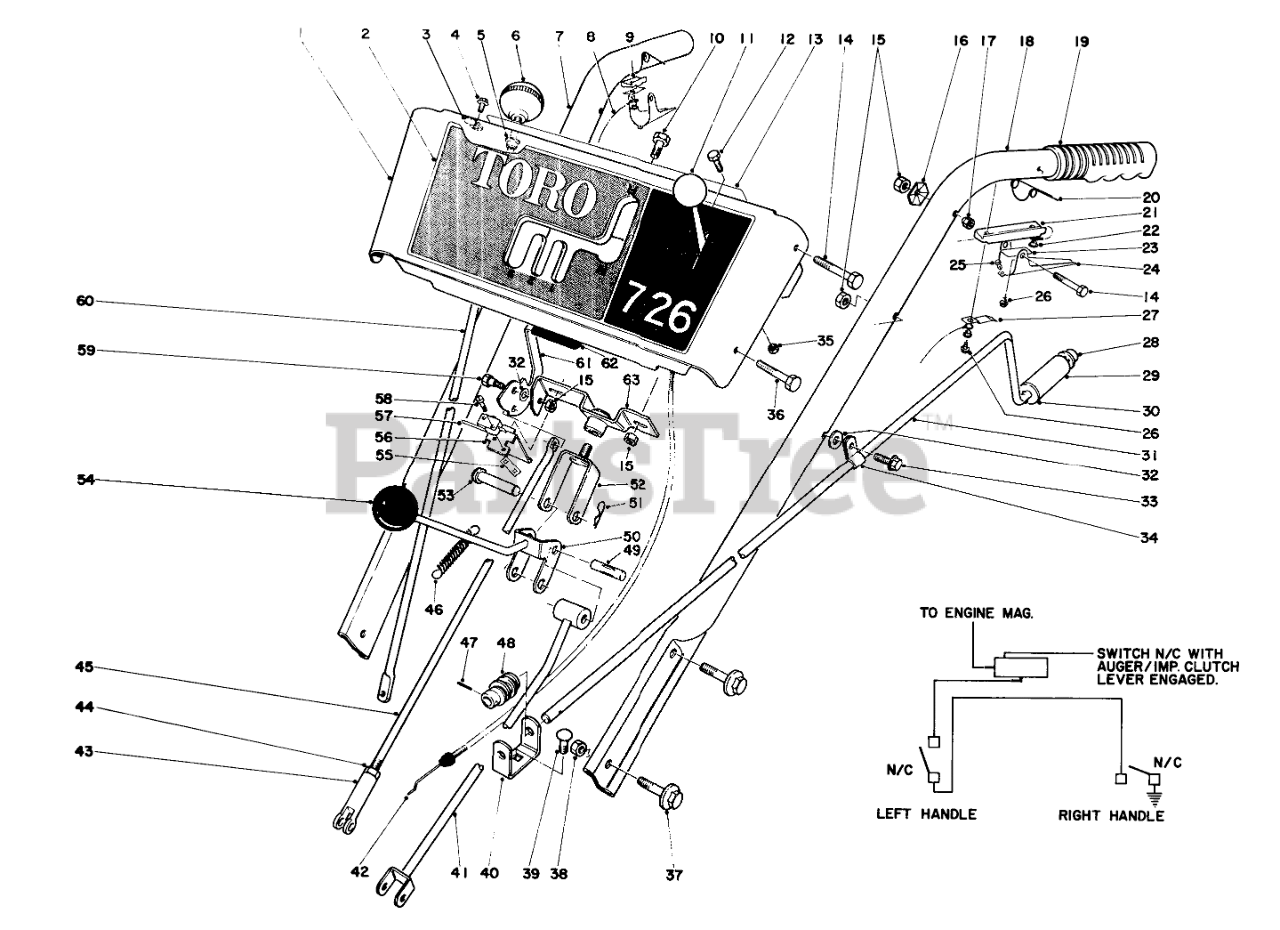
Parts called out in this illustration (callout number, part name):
1	Escutcheon Plate (Incl. Ref. 2 & 13)
2	Decal-Escutcheon
3	PLASTIC CLIP
4	SCREW-HWHTF
5	NYLINER #6LI-FF TYPE 7
6	KNOB-LEVER
7	Handle Right
8	WIRE HARNESS
9	Insulator
10	SCREW-HH
11	KNOB-CONTROL
13	Decal
14	SCREW-HH
15	NUT-LOCK, CONE
16	Washer
17	NUT-CAP
18	Handle Left
19	Grip Handle
20	INTERLOCK SPRING
21	Insulator
22	WASHER INSULATOR
23	INTERLOCK CONTACT
24	Safety Lever
25	1/4 PLASTIC RIVET
26	Screw
27	CONTACT BRACKET
28	RETAINER-PUSH ON
29	CHUTE CONTROL GRIP
30	WASHER-FLAT
31	ROD CHUTE CONTROL
32	WASHER-PLAIN
33	SCREW-HWHTF
34	R-CLAMP
35	Nut
36	SCREW-HH
37	SCREW-HHF
38	NUT-HEX
39	SCREW-CARR
40	WORM BRACKET
41	Trunnion
42	Throttle Contrl
43	Clevis
44	NUT-HJ
45	DRAG LINK
46	CONT ROD SPRING 0
47	PIN-SPRING
48	GEAR-WORM, CHUTE
49	3/8 X 1-1/4 ROL
50	Rod Shift
51	PIN-HAIR
52	Pivot Bracket
53	PIN-CLEVIS
55	NUT-SPEED
56	Switch Bracket
57	MICRO SWITCH
58	SCREW-HEAD, PAN
59	SCREW-SHOULDER
60	Wheel Clutch Rod
61	Auger Clutch Handle
62	AUGER CLUTCH HND GRIP
63	SWIVEL BLOCK WA
